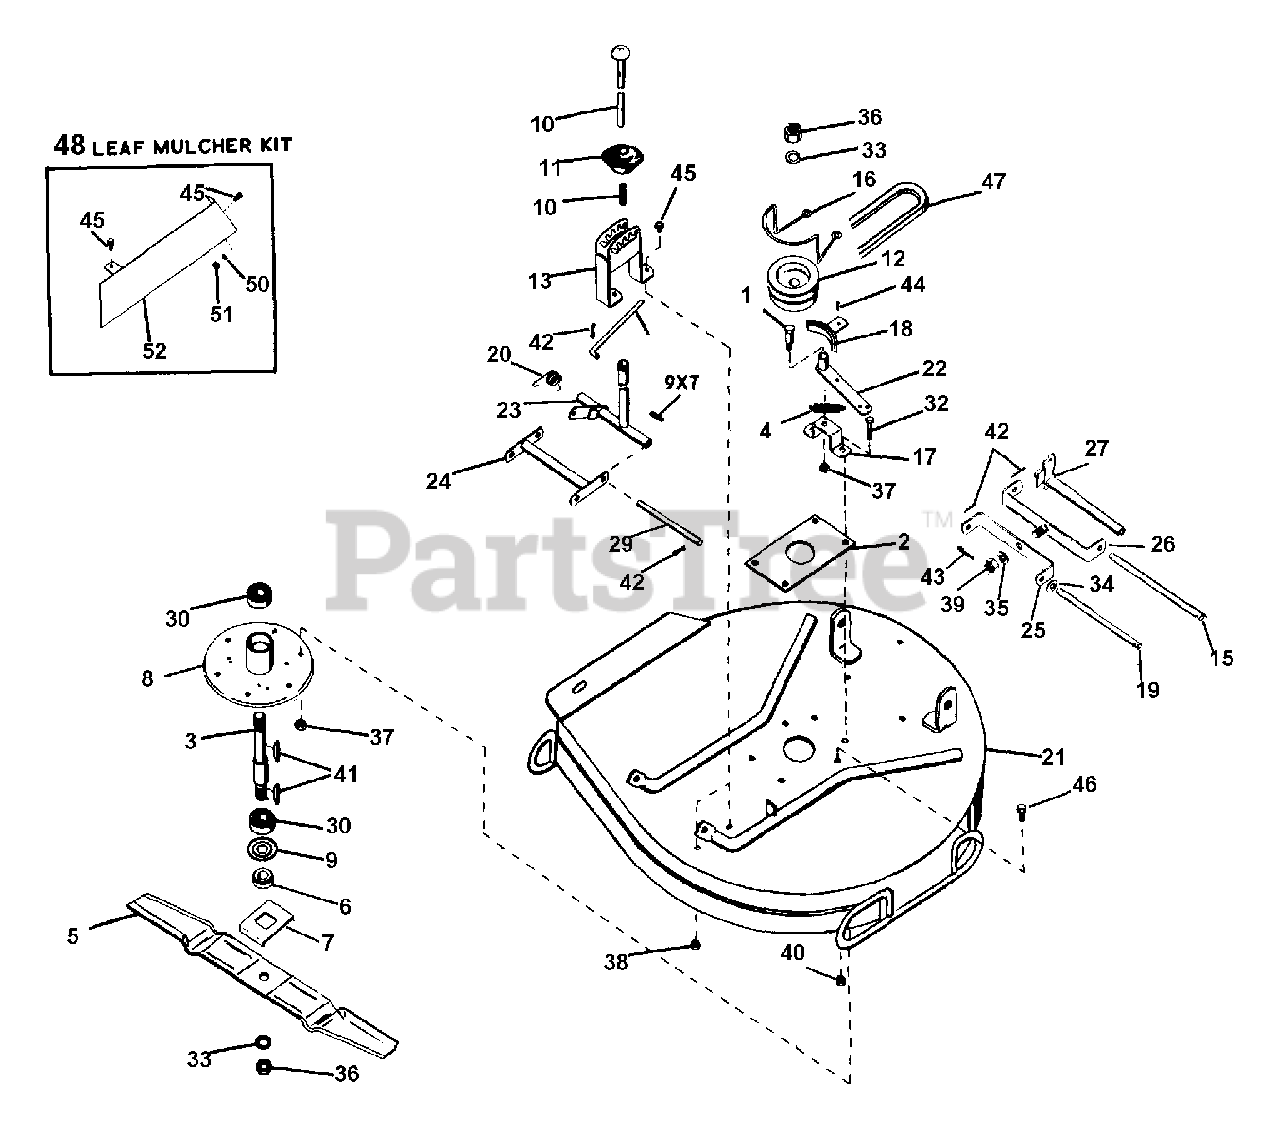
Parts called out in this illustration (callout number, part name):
1	SHOULDER BOLT .50 X 1.75
3	MOWER SPINDLE
4	SPRING
5	BLADE, MOWER
6	RETAINER HUB
7	BLADE TRAY
8	SPINDLE HOUSING
9	BEARING SLINGER
10	SPRING
11	SHIFT BALL
12	MOWER SHEAVE
13	MOWER HGHT QUAD
14	HGHT CNTL PLNGR
15	REAR BRACKET PIN
16	MOWER BELT FINGER
17	BLADE BRAKE SUPPORT
18	BLADE BRAKE
19	HANGER PIN
20	FLOAT LIMIT SPRING
21	MOWER PAN
22	BLADE BRAKE ARM
23	HGHT CNTL ARM
24	FLOATING LINK
27	REAR RAISING BRACKET
28	HGHT LINK ROD
29	ADAPTER PIN
30	BRG-BALL .751X1.78X.61
31	PIN-ROLL .250X1.25
32	BLT-HEX .38-16X1.00 PL
33	WSHR-LK .750X.188 MED PL
34	WSHR-FL-STL .531X1.062X.095 PL
35	BRG-BALL .625X1.375X.44
36	NUT-JAM .625-11
37	NUT-LK-CTR .375-16 GR A PL
38	NUT-LK .312-18 GR A PL
39	NUT-JAM-SL .625-18
40	NUT-LK-FLG .250-20 PL
41	KEY-WDRF .188X.75X.313 SAE 9
42	PIN-COTR .12X1.0 PL
43	PIN-COTR .09X.75 PL
44	RVT .25X.50 RH ST
45	BLT-SERHFWH .31-18X.50 PL
46	SCR-SLTR-SERNK .25-20X.62 PL
47	BELT,5L RAW LAMINATED
48	Leaf Mulcher Kit(Inc. 49,50,51,52)
49	BLT-SERHFWH .31-18X.50 PL
50	WSHR-LK .312X.097 PL HVY
51	NUT-JAM .375-16 PL
52	LEAF MULCHER
